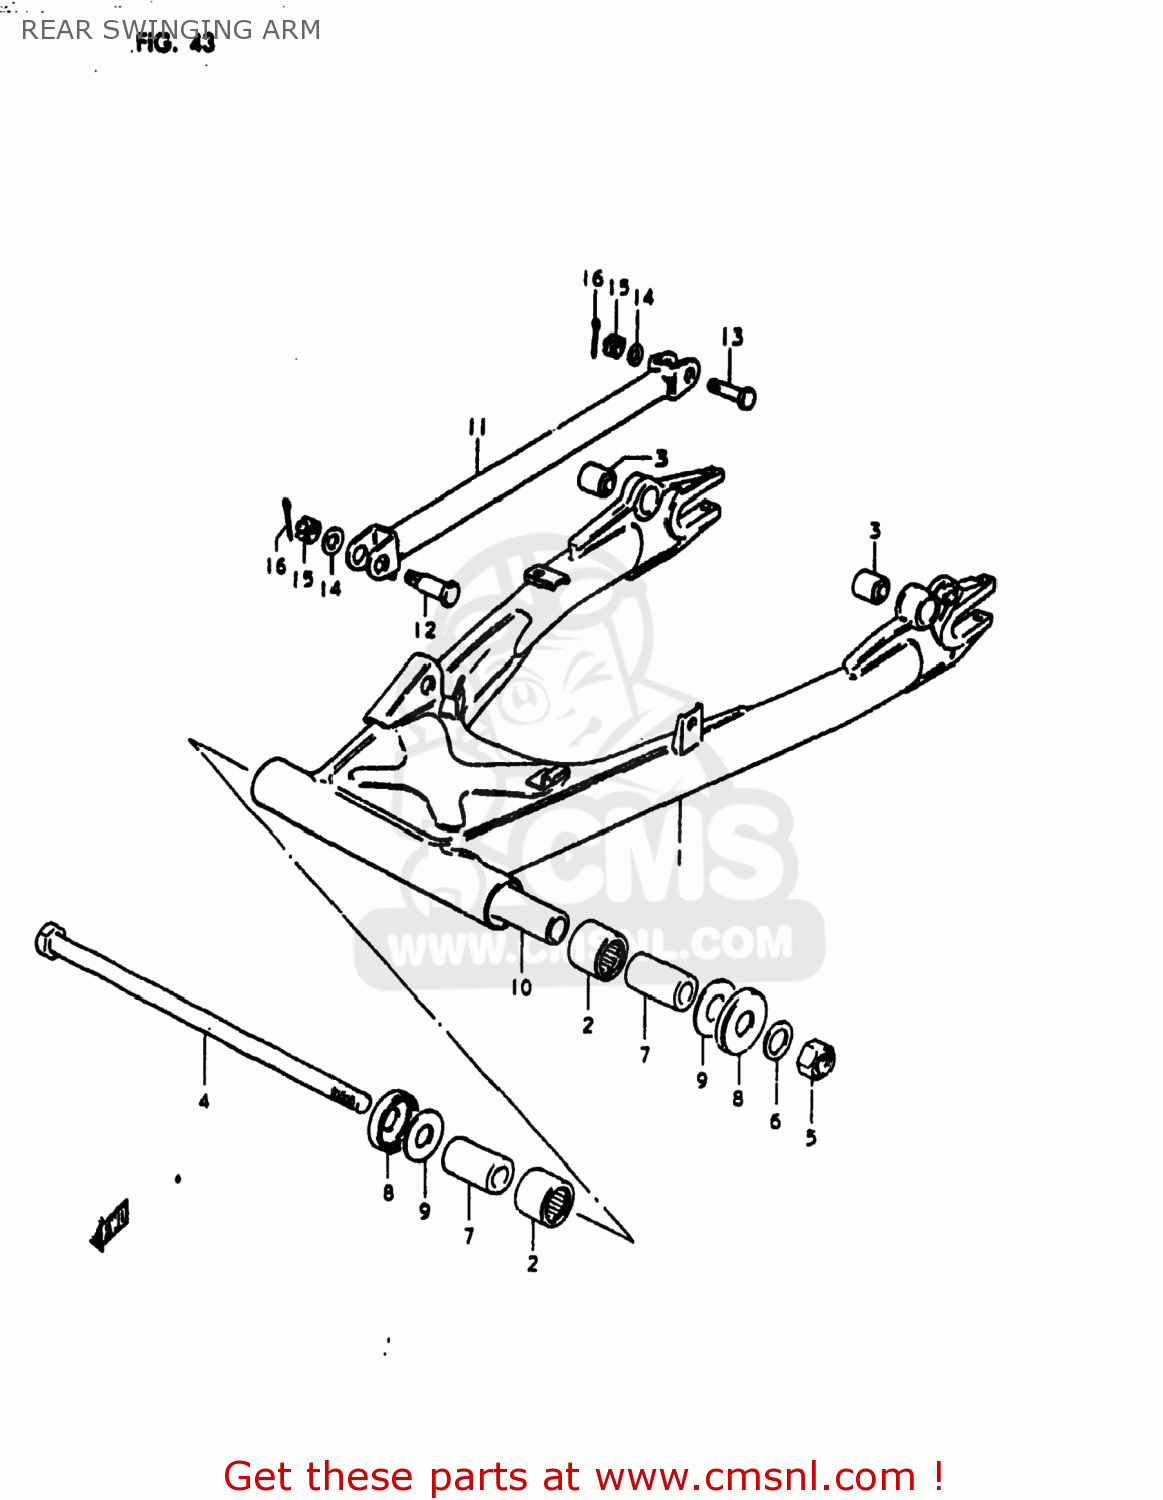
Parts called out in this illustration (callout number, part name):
1	SWING ARM ASSEMBLY,REAR
2	BEARING(25X33X30)
3	BUSH
4	SHAFT,REAR SWING ARM
5	NUT 16MM
6	WASHER
7	SPACER,RR SWGARM PIVOT
8	COVER,REAR SWING ARM DUST
9	WASHER
10	SPACER,RR SWGARM PIVOT CTR
11	LINK,REAR TORQUE
12	BOLT
13	BOLT(10X39)
14	WASHER
15	NUT
16	PIN 20X20
